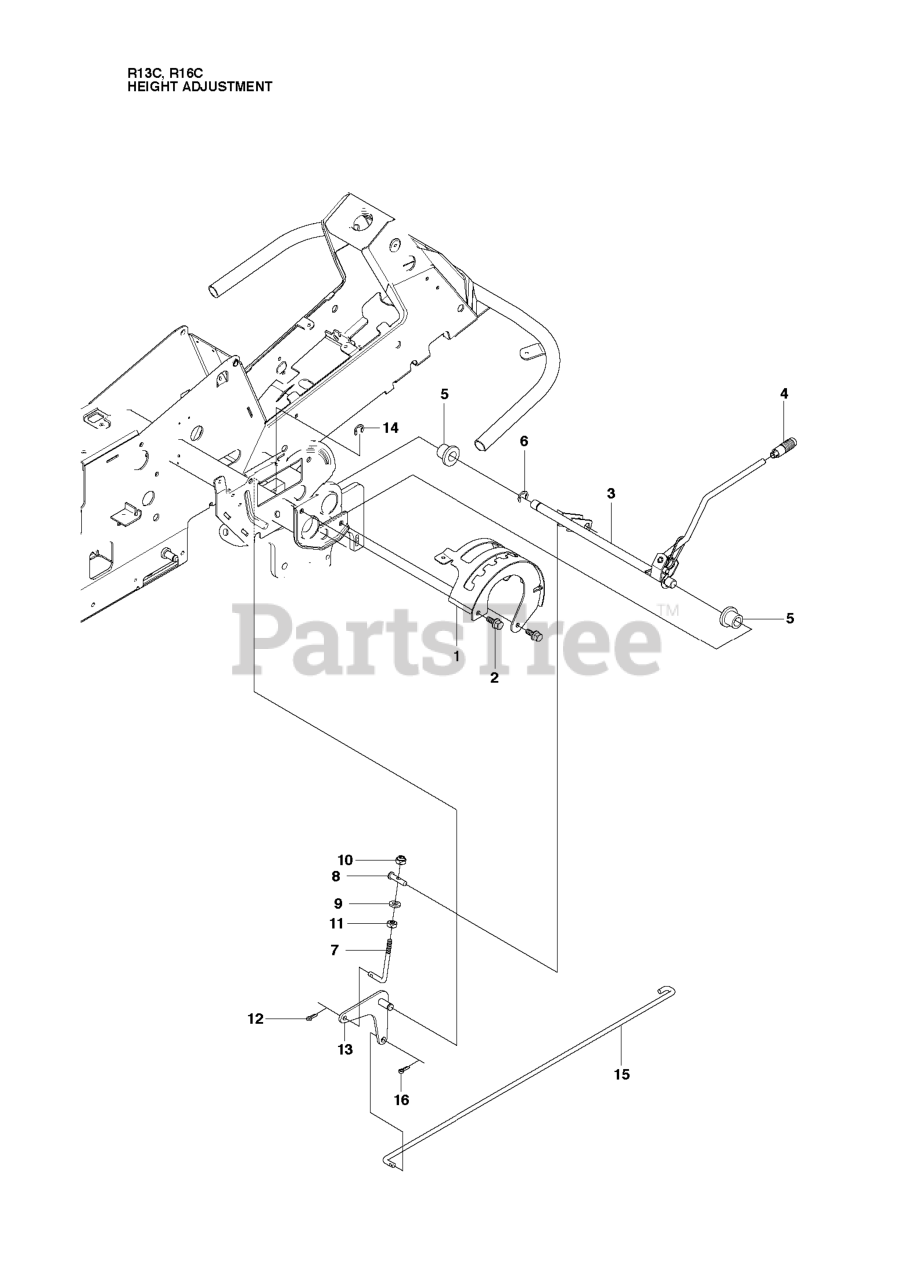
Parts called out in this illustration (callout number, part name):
1	CONTROL PLATE
3	HEIGHT ADJUSTER
4	GEAR STICK KNOB
5	BUSHING
9	WASHER
10	LOCKNUT M8
11	NUT
13	LINK HEIGHT ADJUSTMENT
14	RETAINING RING
15	CONNECTION ROD
